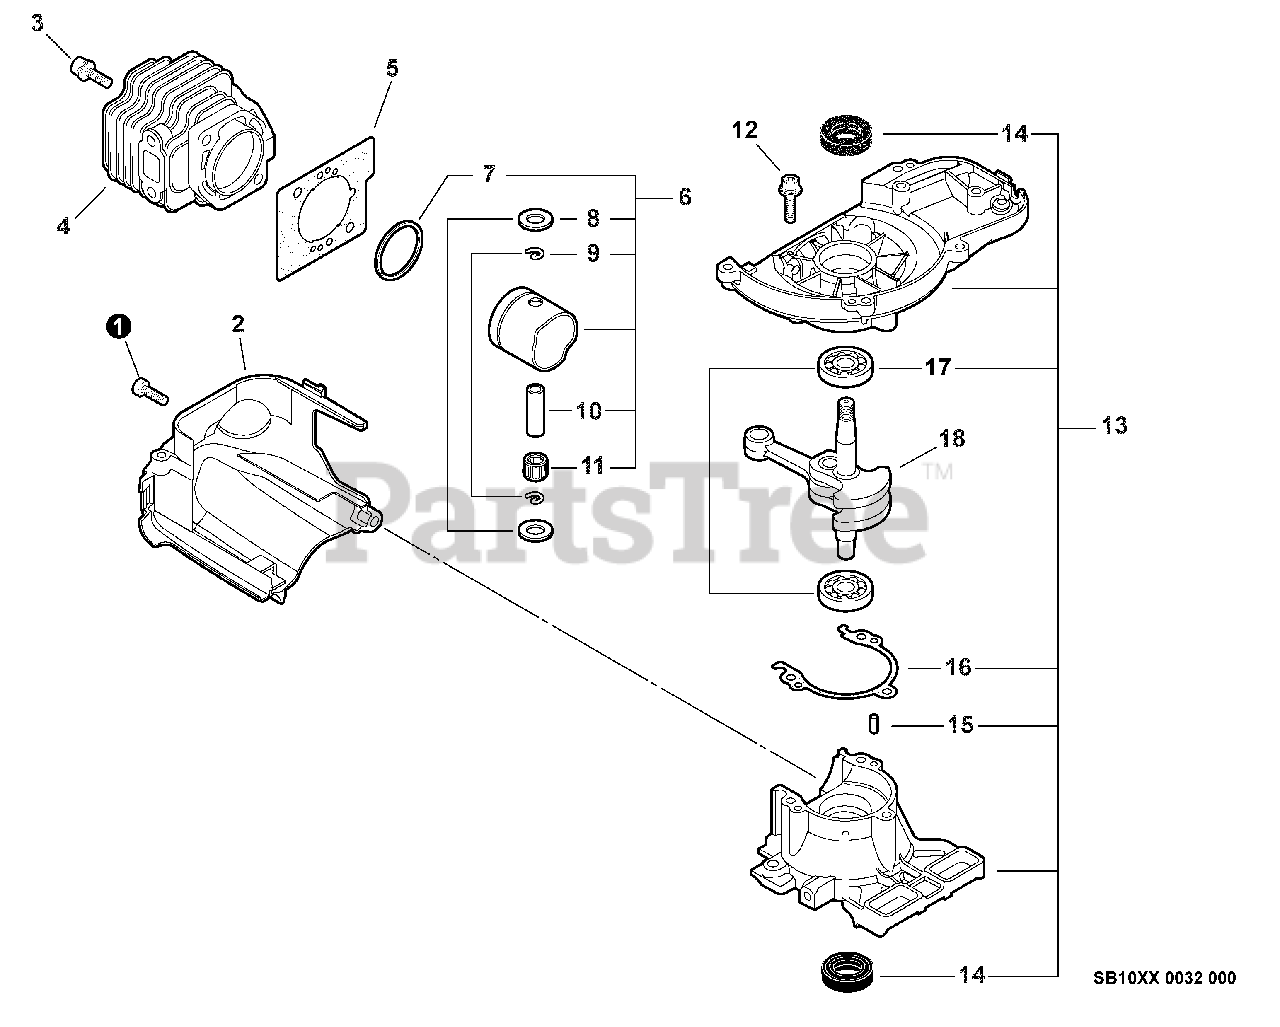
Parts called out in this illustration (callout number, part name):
1	BOLT, TORX 5×16
2	COVER, ENGINE
4	CYLINDER
5	GASKET, CYLINDER
6	PISTON KIT
7	RING, PISTON
8	WASHER, THRUST
9	RING, SNAP
10	PIN, PISTON 8
11	BEARING, NEEDLE
12	BOLT 5×28
13	CRANKCASE KIT
14	SEAL, OIL
15	PIN, LOCATING 4×8
16	GASKET, CRANKCASE
17	BEARING, BALL
18	CRANKSHAFT ASSY
